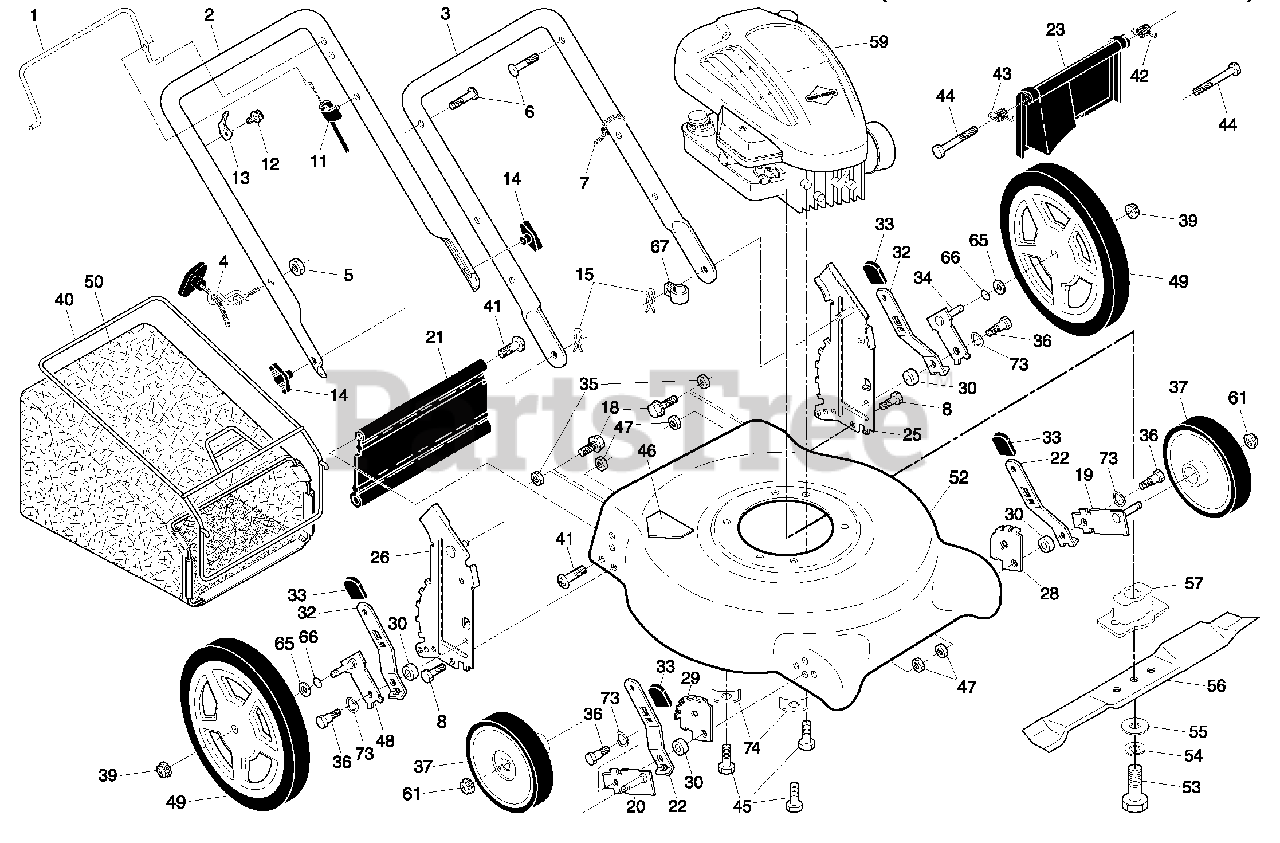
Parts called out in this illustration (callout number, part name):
1	Control Bar
2	Upper Handle
3	Lower Handle
4	Rope Guide
6	Handle Bolt
7	Wire Tie
8	Bolt, Hex Head 5/16-18 x 3/4
11	Engine Zone Control Cable
12	Hex Washer Head Screw #10-24 x 1/2
13	Up-Stop Bracket
14	Handle Knob
15	Hairpin Cotter
18	Screw
19	Axle Arm Assembly, Front, LH
20	Axle Arm Assembly, Front, RH
21	Rear Skirt
22	Selector Spring, Front
23	Rear Door Assembly
25	Handle Bracket Assembly, LH
26	Handle Bracket Assembly, RH
28	Wheel Adjusting Bracket, Front, LH
29	Wheel Adjusting Bracket, Front, RH
30	Spacer
32	Selector Spring, Rear
33	Selector Knob
34	Axle Arm Assembly, Rear, LH
35	Nut, Hex
36	Shoulder Bolt 5/16-18
37	Wheel & Tire Assembly, Front 7 x 1-3/4
39	Nut, Hex
40	Frame, Grassbag
41	Screw, Hinge
42	Spring, LH
43	Spring, RH
44	Bolt, Rear Door
45	Hex Head Thread Rolling Screw 3/8-16 x 1
46	Danger Decal
47	Locknut, Hex 5/16-18
48	Axle Arm Assembly, Rear, RH
49	Wheel & Tire Assembly, Rear 12 x 1-3/4
50	Grassbag
52	Housing Assembly
53	Hex Head Screw 3/8-24 x 1-3/8 Grade 8
54	Helical Lockwasher
55	Hardened Washer
56	21" Blade
57	Blade Adapter
61	Flanged Locknut
65	Washer, Flat
66	O-Ring
67	Clip, Cable
73	Washer, Curved, Cylindrical
74	Washer, Special, Engine
74	Operator's Manual, English
74	Operator's Manual, French
74	Repair Parts Manual
